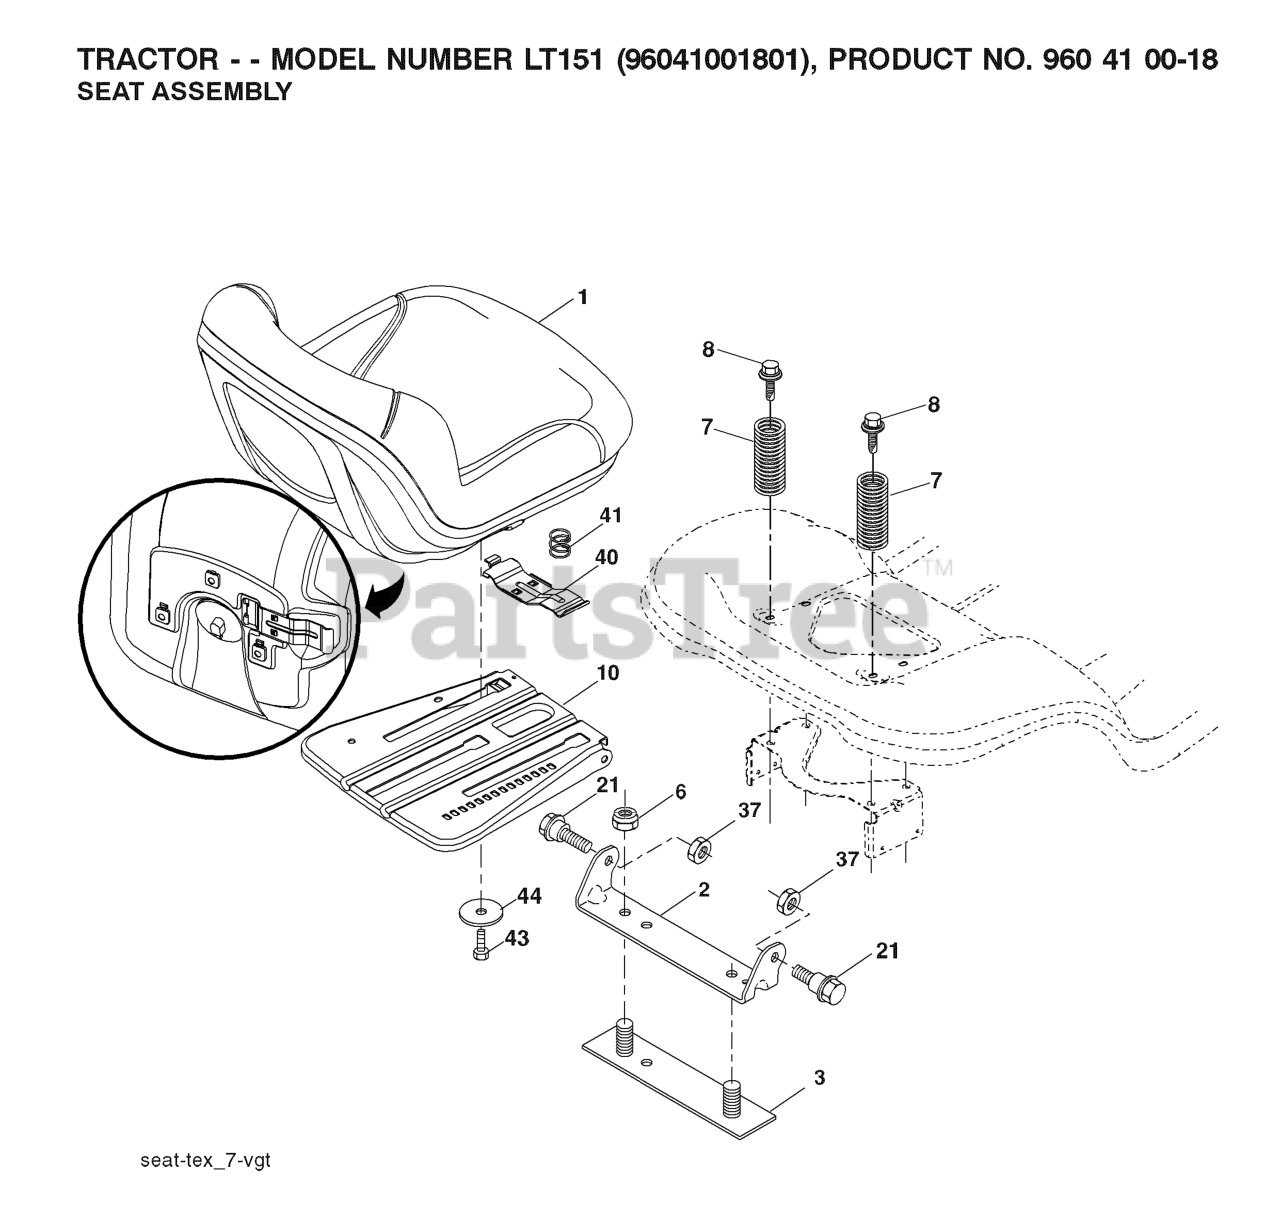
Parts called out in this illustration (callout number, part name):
1	SEAT.TH130.GRY.MILSCO.
2	BRKT.PIVOT.FENDER
3	STRAP
6	NUT
7	SPRING COMPRESSION
8	BOLT.5/16-18UNCX3/4 W/SEMS.BLK
10	PAN.ASM.SEAT.3PT
21	BOLT.SHOULDER.5/16-18
37	NUT.71038.31-18.HEX.NYLOCK
40	HANDLE.SLIDE.SEAT.TEX.BLACK
41	SPRING.LATCH.SEAT.TEX
44	WASHER 13/32 X 2-3/8 X 12GA
